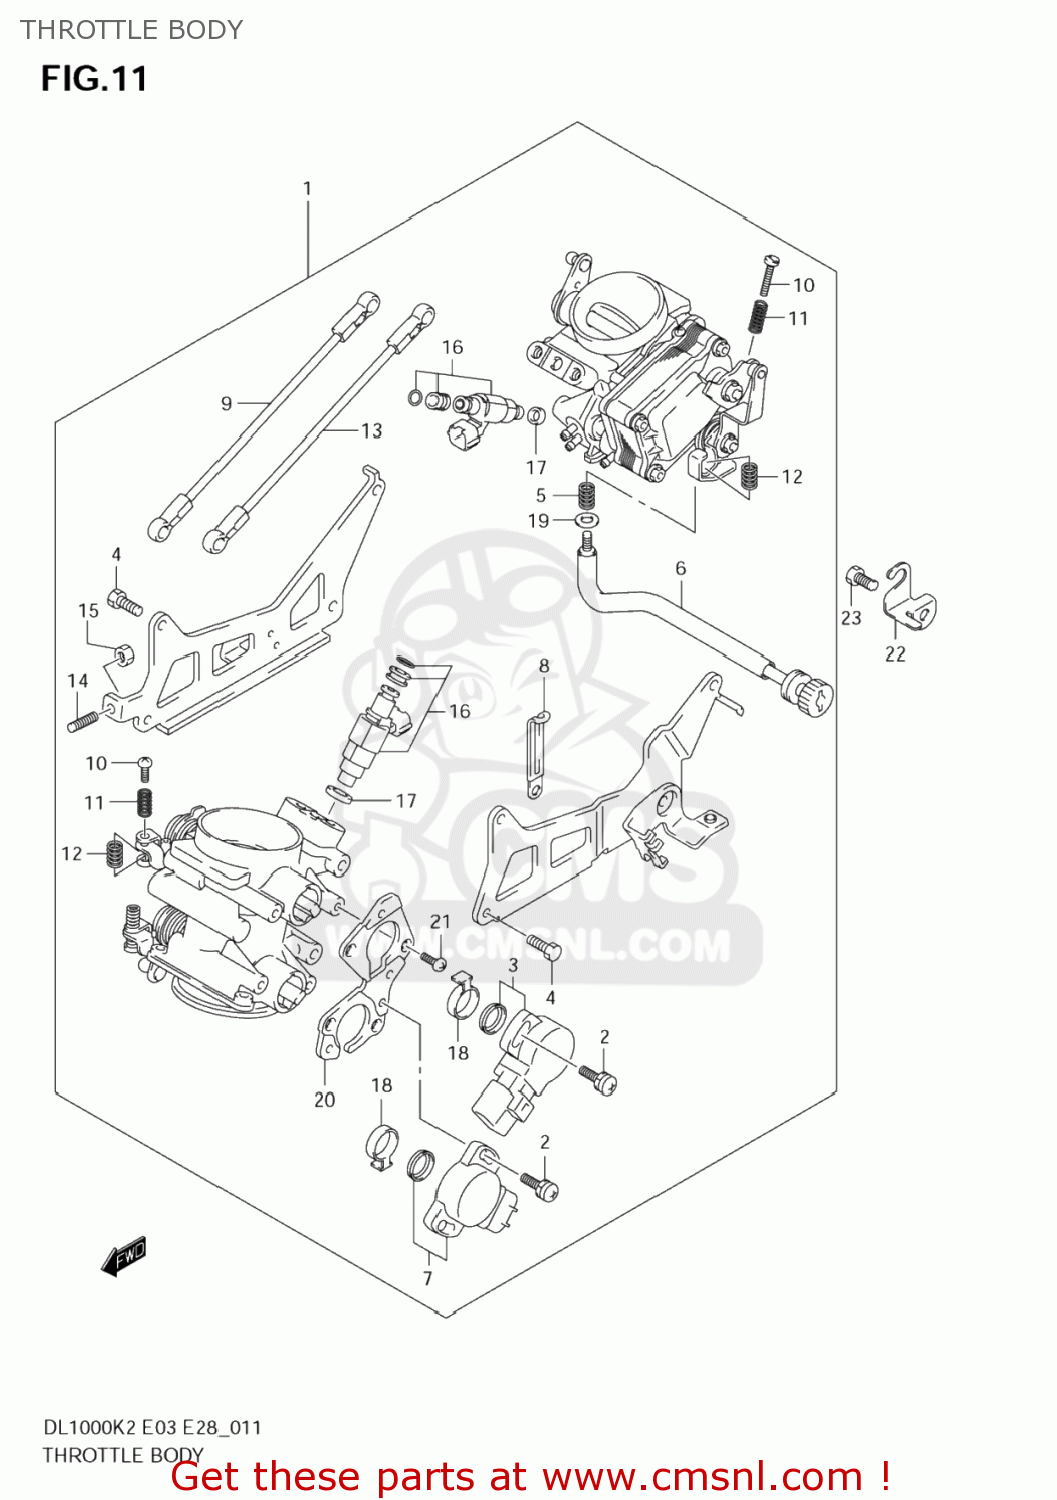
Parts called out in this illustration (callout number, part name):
1	INJECTION ASSY
2	SCREW
3	SENSOR ASSY
4	BOLT
5	SPRING
6	SCREW ASSY,ADJUST
7	SENSOR ASSY,THROTTLE
8	CLAMP(L:45)
9	ROD ASSY
10	SCREW
11	SPRING
12	SPRING
13	ROD ASSY
14	SCREW,ADJUST
15	NUT
16	INJECTOR ASSY
17	CUSHION,FUEL INJECTOR
18	RING
19	WASHER
20	PLATE
21	SCREW
22	PLATE,IDLE ADJUST
23	BOLT
